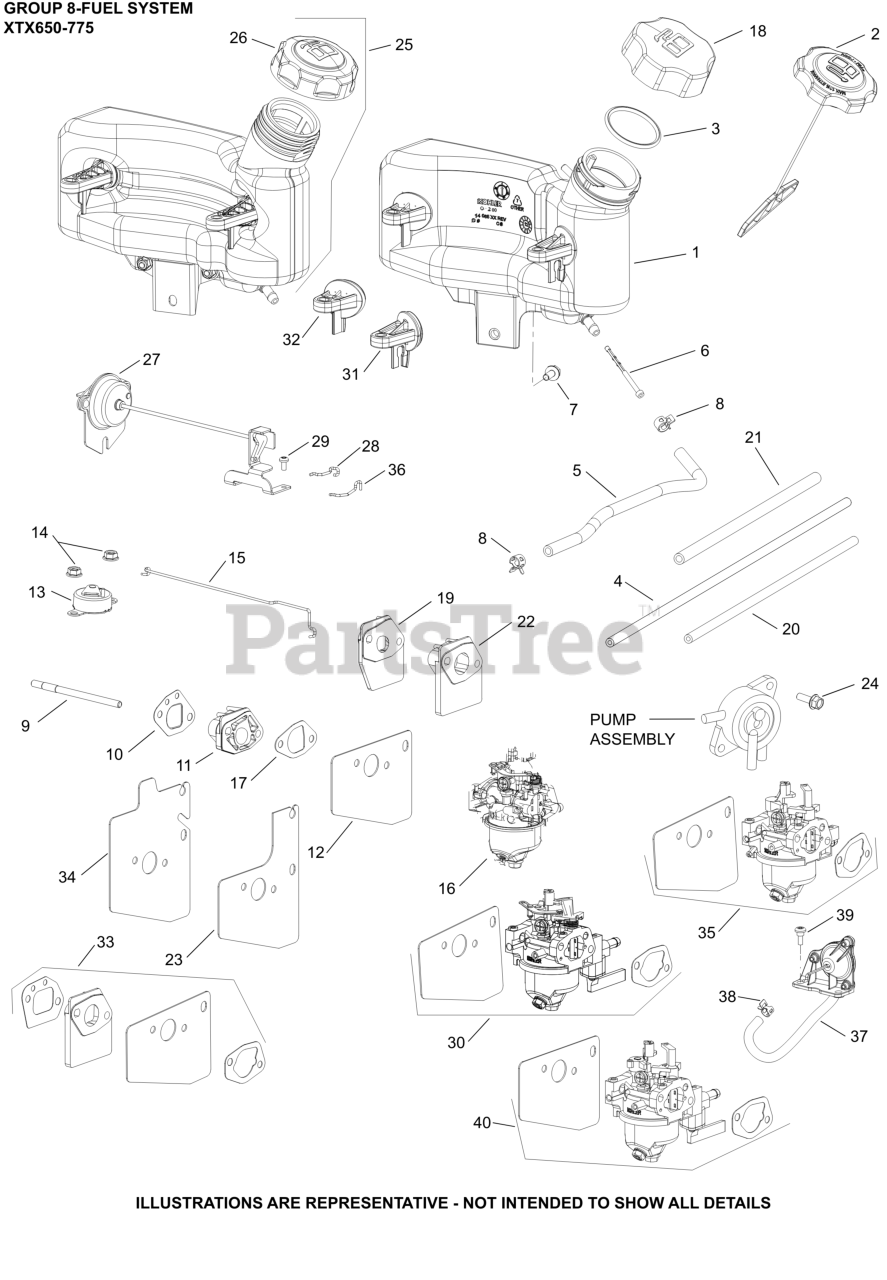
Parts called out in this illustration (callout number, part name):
1	TANK, FUEL 1.4L FOR EUROPE ONLY
2	CAP ASSEMBLY, FUEL
3	SEAL, FUEL CAP- (#DSC)
4	HOSE, EVAPORATIVE 20"- (#24326143S)
5	HOSE, FUEL LOW-PERMEATION (CKY)
6	FILTER, FUEL IN-NIPPLE
8	CLAMP, HOSE (NON-CALIF)(#1423710S)
9	STUD,M6X1.0X100.2MM
10	GASKET, SPACER - USE 14 041 24-S
11	SPACER, CARBURETOR
12	KIT, CARBURETOR HEAT SHIELD GASKET
16	KIT, CARBURETOR COMPLETE
17	KIT, INTAKE GASKET
NI	KIT, HIGH ALT (4000-8000 FT)
NI	KIT, CARBURETOR REPAIR (RUIXING)
